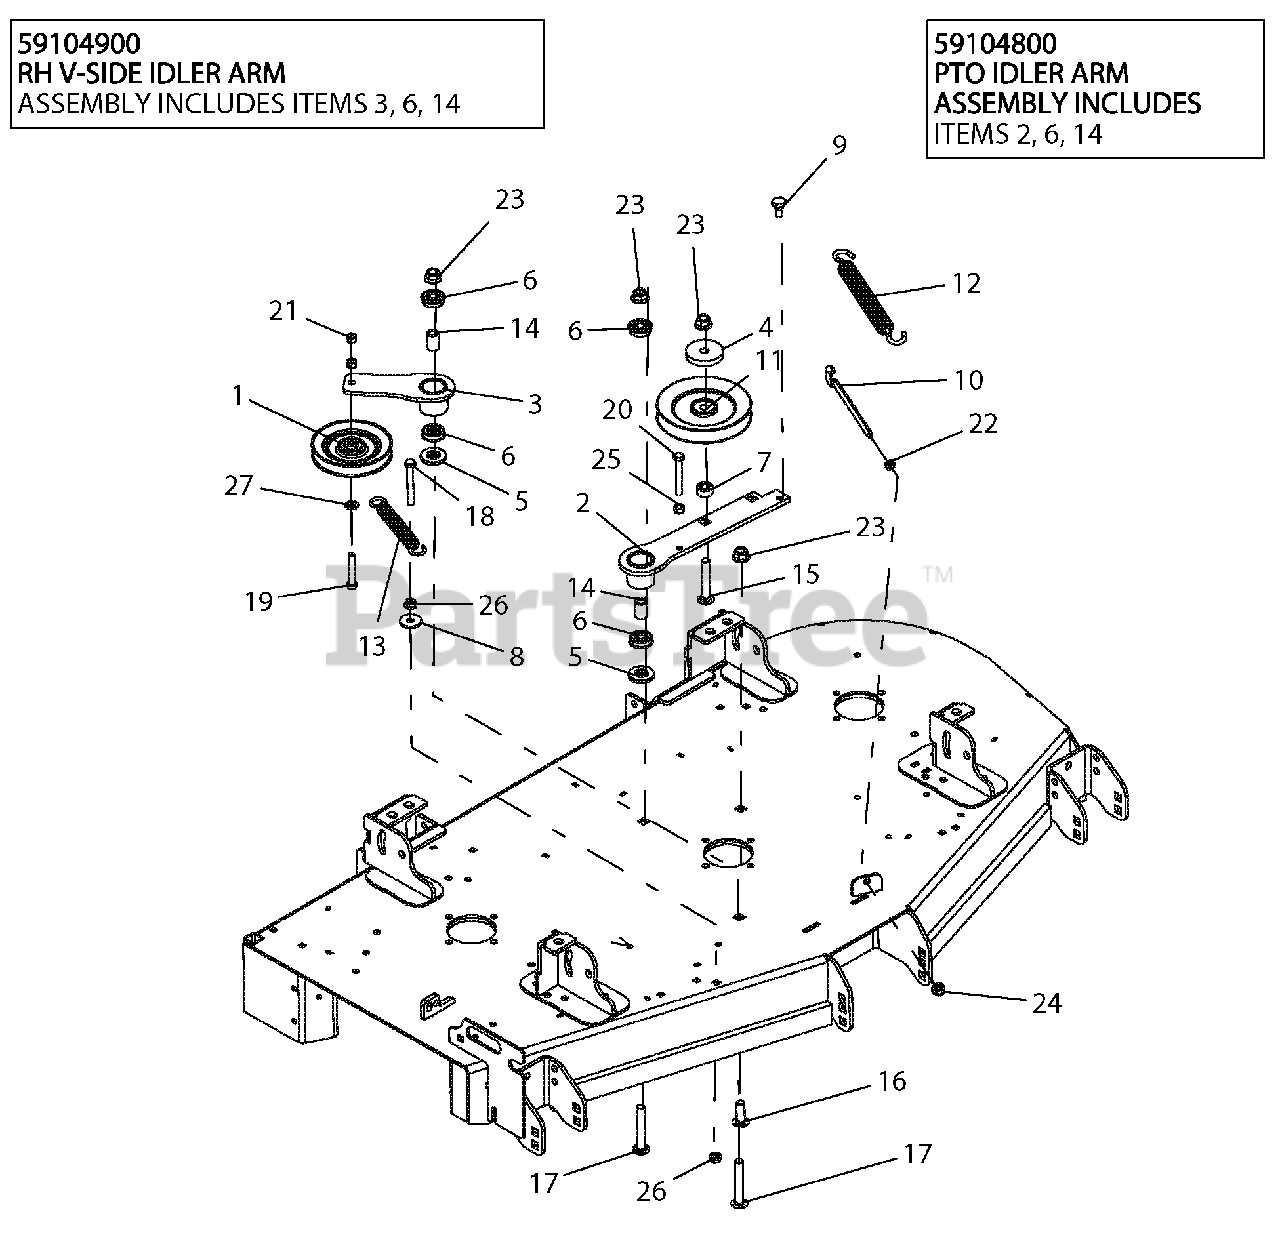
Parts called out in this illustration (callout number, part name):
1	IDLER, V-5.00" W/.69 STANDOFF
2	WLDMT, DECK PTO IDLER ARM-BLACK
3	WLDMT, DECK RH IDLER ARM-BLACK
4	CAP, IDLER BEARING SEALING
5	SPACER, IDLER ARM
6	BRG, BALL .501 X 1.38 X .438 SEALED
7	BSHG, SPCR .502 X .997.50 PM
8	WSHR-FL-STL .406X1.375X.135 YZ
9	BLT, SHLDR EP .38-16X.30 HEX YZ
10	BOLT, .38-16X6.00 .62 DIA EYE
11	SHEAVE, .50" ID X 6.00" OD V-IDLER
12	SPRG, EXTENSION
13	SPRG, EXTENSION
14	SPACER, .510 X .750 X 1.148
15	BLT-RDHDSQNK .50-13X3.00 G5 Y
16	BLT-RDHDSQSHNK .50-13X1.50 YWZC
17	BLT-RDHDSQSHNK .50-13X3.25 YWZC
18	BLT-HEX .38-16X3.00 GR5 YWZC
19	BLT-HEX .38-16X2.25 GR5 YWZC
20	BLT-HEX .38-16X2.75 GR5 YWZC
21	NUT-LK-CTR .38-16 YWZC
22	NUT, JAM .375-16 YWZC
23	NUT-LK-NYL-FLG .50-13 YWZC
24	NUT-LK-NYL-FLG .38-16 YWZC
25	NUT-HEX .38-16 YWZC
26	@NUT-SPNLK-FLG .375-16 YWZC
27	WSHR-FL-STL.406X.812X.065 YWZ
